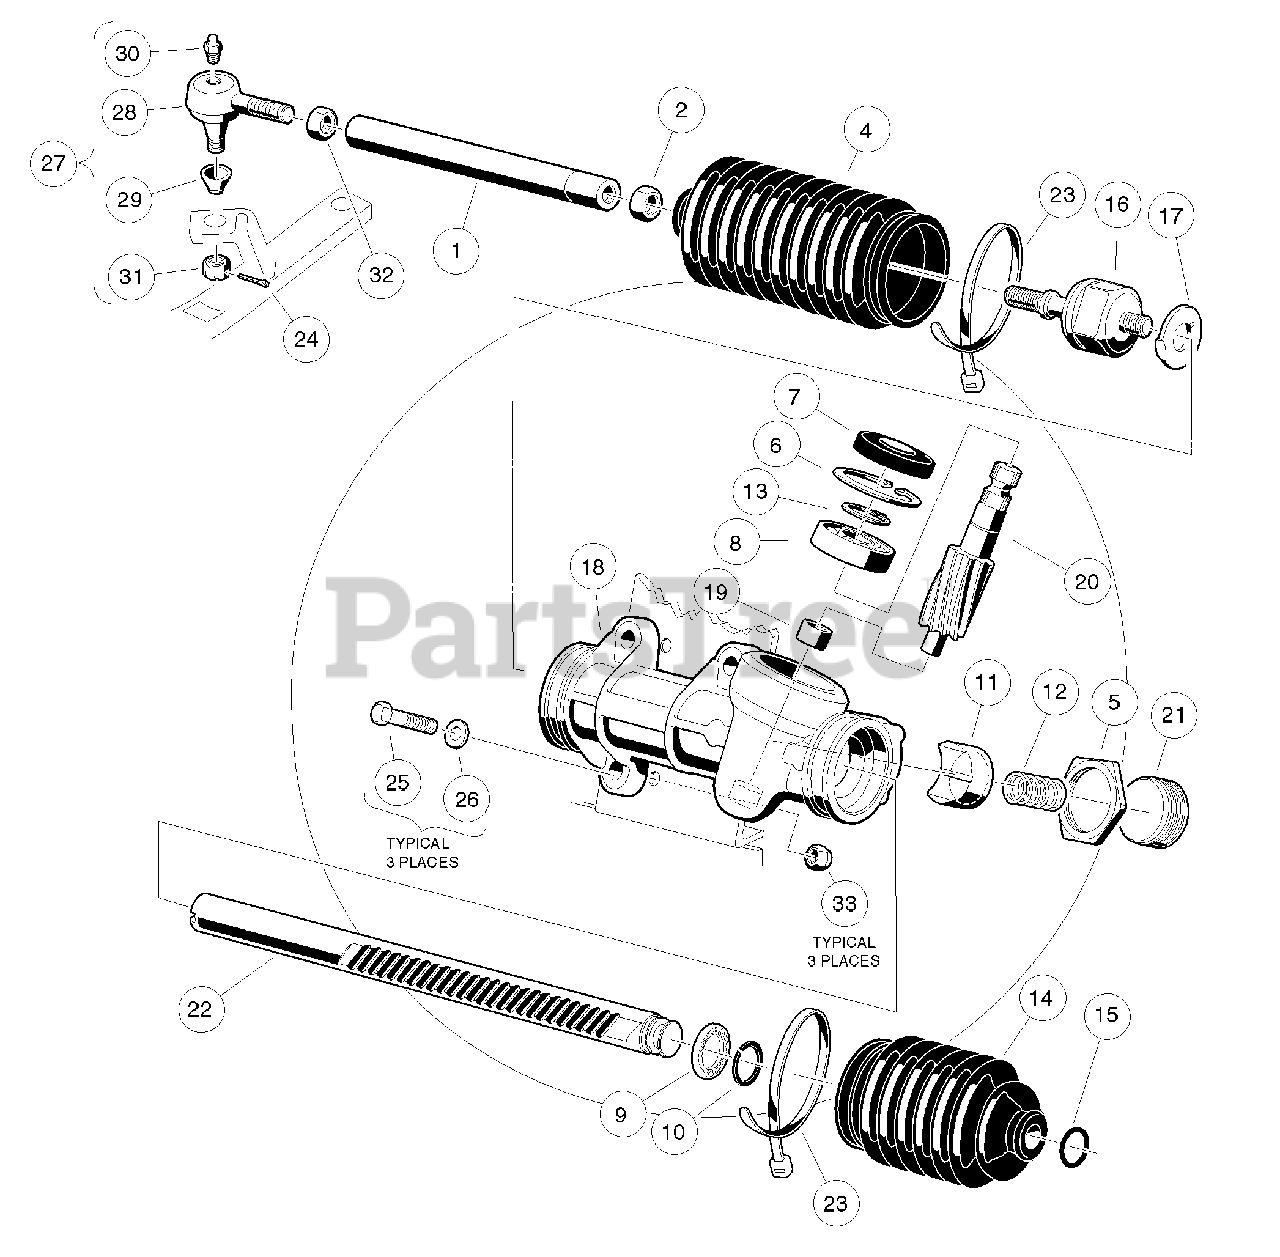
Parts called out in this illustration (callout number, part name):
1	Link, Rack and Pinion Drag
2	Nut, 12mm Hex
3	Steering Gear Assembly
4	Bellows, Long
5	Rack Screw Locknut
7	Seal, Steering Pinion Dust
8	Bearing, Ball
9	Stop Washer
10	Stop Ring, C-Type
11	Support Yoke
12	Rack Guide Pressure Spring
13	Ring, Stop, C-Type
14	Bellows, Short
15	Dust Seal Retaining Ring
16	Inner Ball Joint Asm
17	Washer, Tab
18	Box, Steering Gear
19	Bearing, Lower Pinion
20	Pinion, Steering
21	Screw, Rack Guide
22	Rack, Steering
23	Tie Wrap, 8" Nylon
24	Pin, 3/32 X 1.00 Sq Cut Cotter
25	Screw, 3/8-16 X 1.50 Hex-Head Cap
26	Washer, 3/8 Type A Flat
27	Ball Joint, Left
28	Socket, LH Vertical
29	Seal, Vertical Socket Dust
30	Fitting, 1/4-28 Thread-Forming Grease
31	Nut, 3/8-24 UNF Hex
32	Nut, 1/2-20 Hex, Left-Hand Thread
33	Locknut, 3/8-16 Hex
